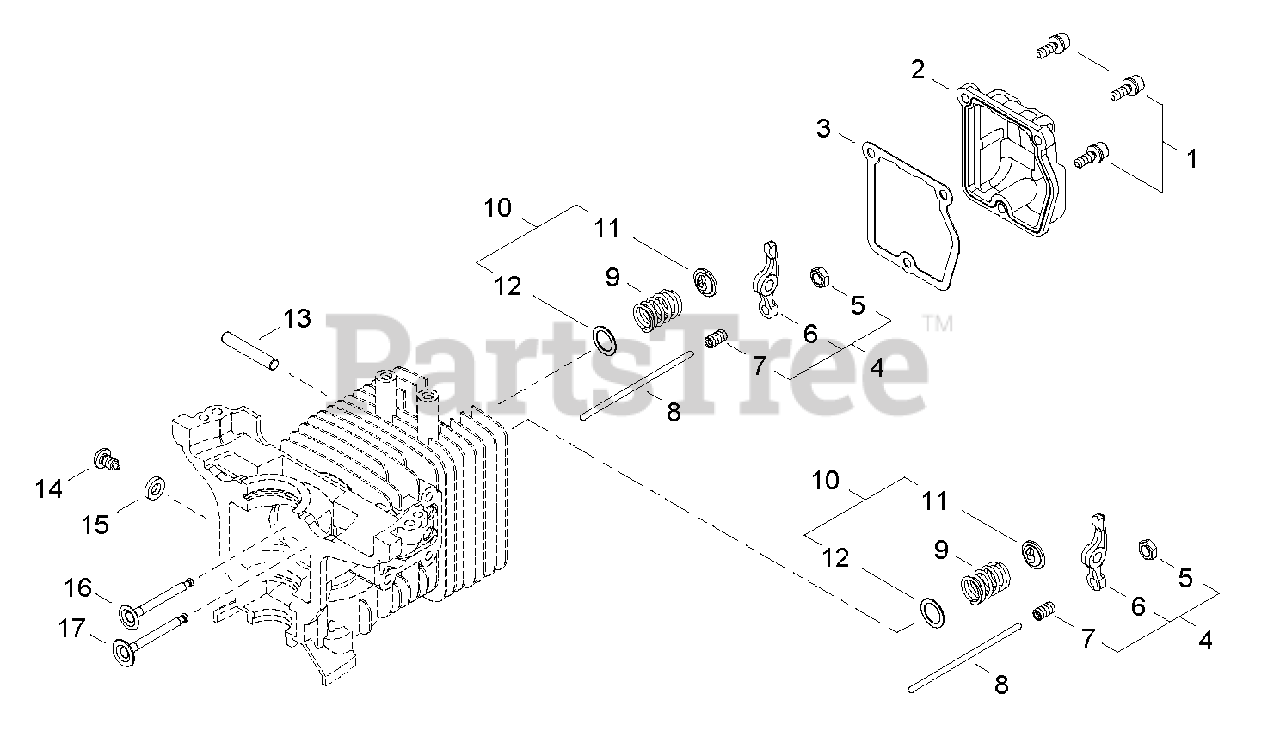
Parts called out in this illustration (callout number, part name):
1	BOLT M4×14
2	COVER, ROCKER ARM
3	GASKET, ROCKER ARM
4	ARM ASSY, ROCKER
5	NUT, ADJUSTER LOCK 5
6	ARM, ROCKER
7	SCREW, ADJUSTER
8	PUSHROD
9	SPRING, VALVE
10	RETAINER SET, VALVE
11	RETAINER, VALVE
12	WASHER, VALVE 9
13	SHAFT, ROCKER ARM Ø5×31.8 MM
14	SCREW M5
15	WASHER Ø10ר5.5×2
16	VALVE, EXHAUST
17	VALVE, INTAKE
